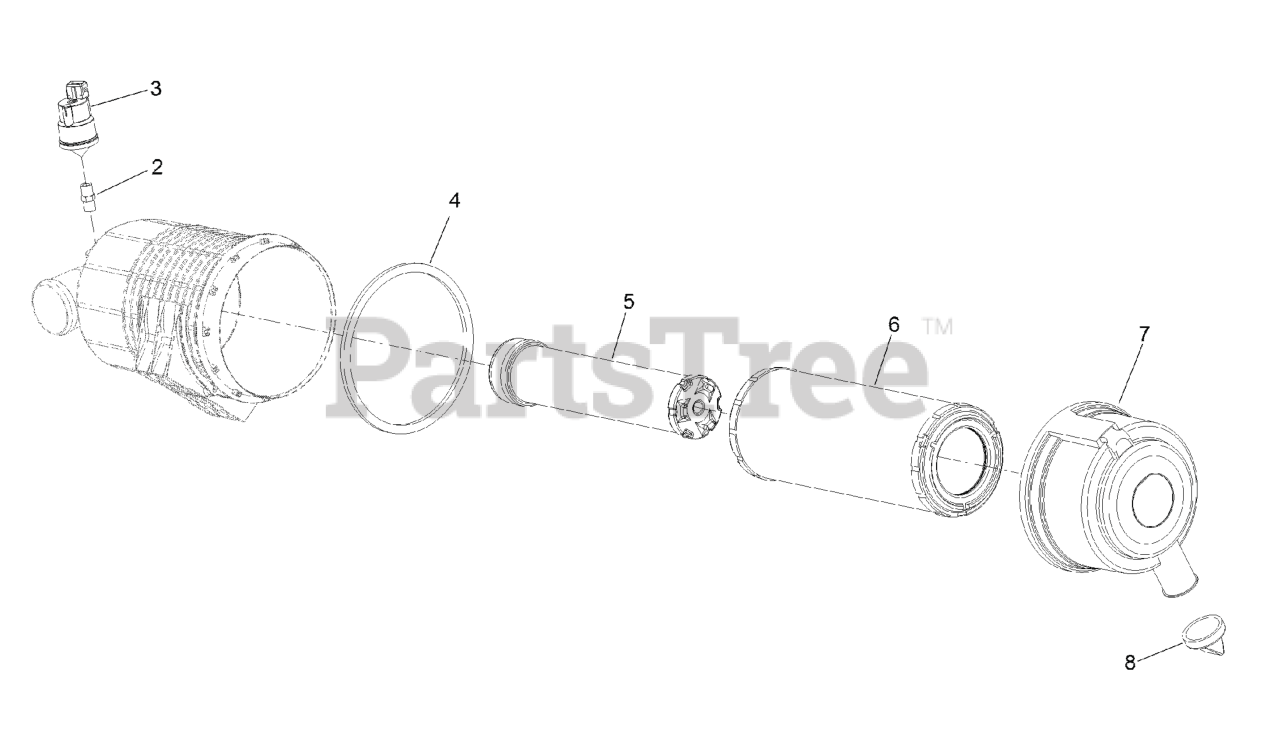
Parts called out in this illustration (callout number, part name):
2	NIPPLE-PIPE
3	INDICATOR-MINI
8	VALVE-VACUATOR
